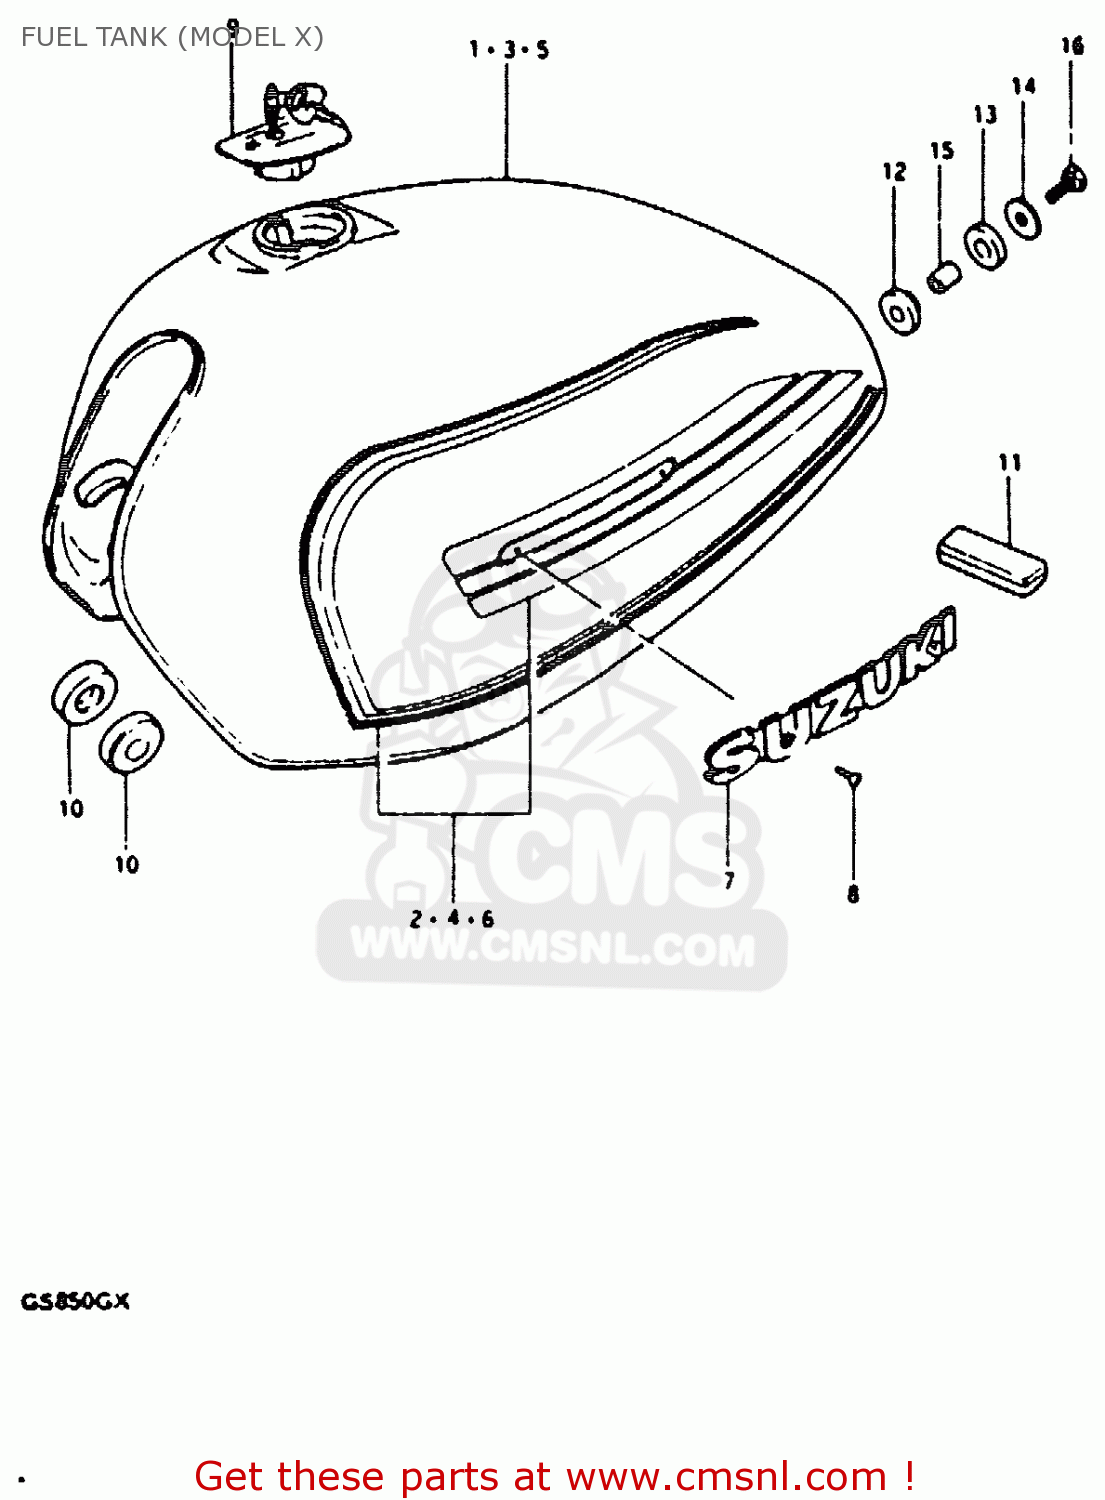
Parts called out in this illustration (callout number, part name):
1	TANK, FUEL (BLACK)
2	TAPE SET
3	TANK, FUEL (RED)
4	TAPE SET
5	TANK, FUEL (SILVER)
6	TAPE SET
7	EMBLEM,FUEL TANK
8	SCREW
9	CAP SET,FUEL TANK
10	CUSHION
11	CUSHION
12	CUSHION
13	CUSHION
14	WASHER (8.5X29X1.6)
15	SPACER(8.5X12X19)
16	BOLT (8X30)
